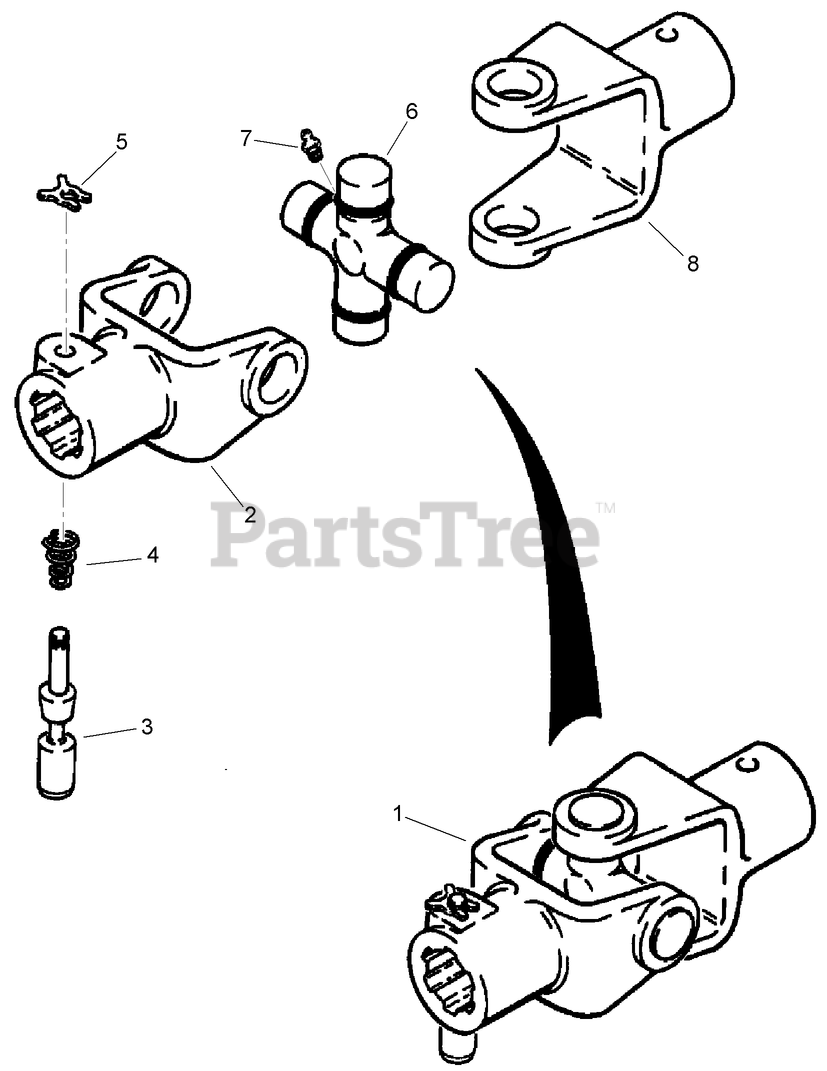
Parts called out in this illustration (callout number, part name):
1	U-JOINT ASM
2	YOKE - Splined
3	PIN - Retainer
4	WASHER - Special
5	RING - Snap, Pin Retaining
6	CROSS - Universal Joint
7	FITTING-grease, straight, 1/4-28 taper x 15/16 inch
8	YOKE-boring attachments
